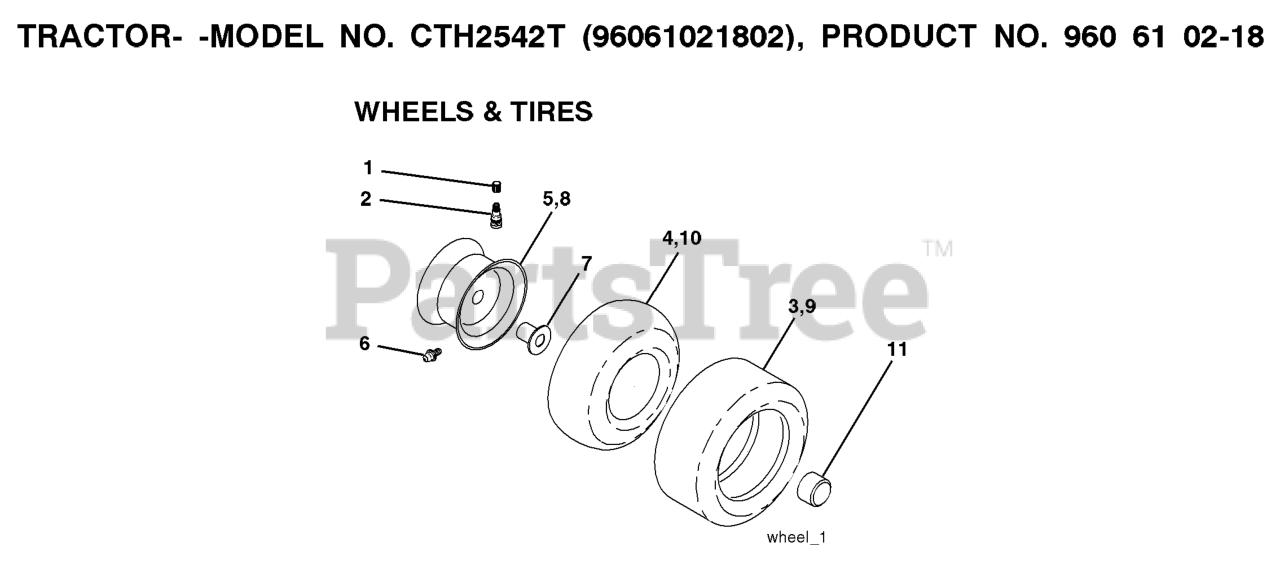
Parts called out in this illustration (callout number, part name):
2	VALVE STEM LT
3	TIRE HEAVY DUTY
4	TUBE.5.3/4.5/6
5	RIM ASM 6" FRONT SILVER
6	FITTING LT
7	BEARING T
8	RIM ASM 8" REAR SILVER
9	TIRE.TS.20X10-8
10	TUBE
11	CAP, AXLE BLK
